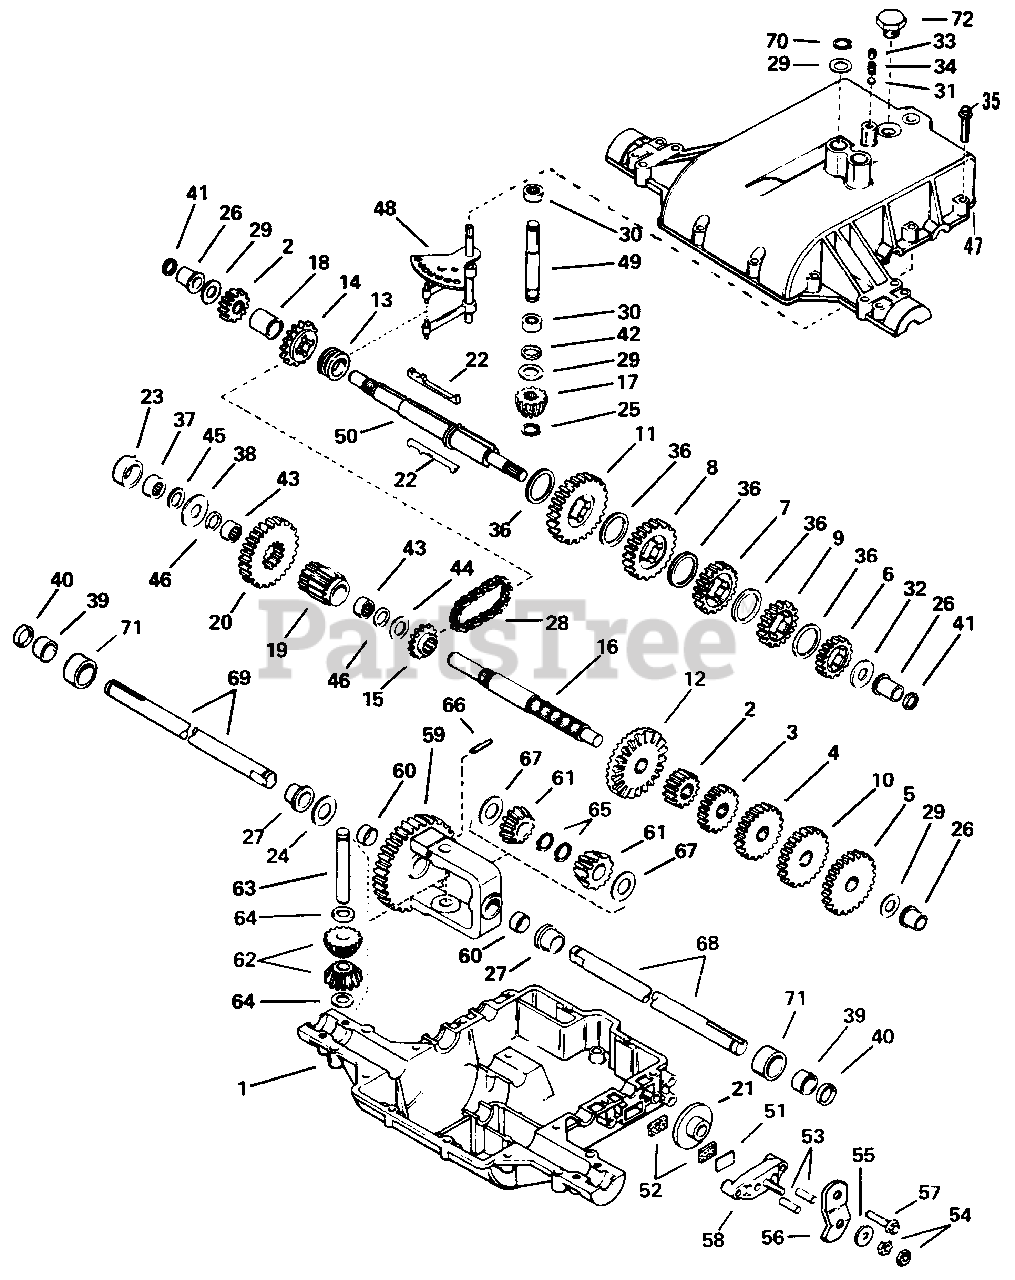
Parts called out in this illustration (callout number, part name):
1	CASE, Transaxle
2	GEAR, Spur (15 Teeth)
3	GEAR, Spur (20 Teeth)
4	GEAR, Spur (25 Teeth)
5	GEAR, Spur (30 Teeth)
6	GEAR, Spur (20 Teeth)
7	GEAR, Spur (25 Teeth)
8	GEAR, Spur (30 Teeth)
9	GEAR, Spur (22 Teeth)
10	GEAR, Spur (28 Teeth)
11	GEAR, Spur (35 Teeth)
12	GEAR, Bevel (42 Teeth)
13	COLLAR, Shift
14	SPROCKET (18 Teeth)
15	SPROCKET (19 Teeth)
16	SHAFT, Counter
17	BEVEL PINION, Input
19	PINION, Output
20	GEAR, Output
21	DISK, Brake
25	RING, Retaining
26	BUSHING, Flanged
27	BUSHING, Flanged
28	CHAIN, Roller (No. 41 chain, 24 links)
29	WASHER, Thrust
30	BEARING, Needle
31	BALL, Steel
32	WASHER, Thrust
33	SETSCREW, 3/8-16 x 3/8
35	SCREW, Hex hd., Thd. Form., 1/4-20 x 1-1/4
36	WASHER, Thrust
37	BEARING, Needle
38	WASHER, Flat
39	BEARING, Needle
40	SEAL, Oil
41	RING, Square Cut
42	RING, Square Cut
43	BEARING, Needle
44	WASHER, Flat
45	RING, Square Cut
46	RING, Square Cut
47	COVER, Transaxle
48	ROD & FORK ASSY., Shift
49	SHAFT, Input
50	SHAFT, Brake
51	PLATE, Brake Pad
52	PAD, Brake
53	PIN, Dowel
54	LOCKNUT, 5/16-24
55	WASHER, Flat
56	LEVER, Brake
57	SCREW, Hex Hd., Thd. Form., 1/4-20 x 1-1/4
58	HOLDER, Brake Pad
59	GEAR ASSY., Differential (Incl. 2 of No. 60)
61	GEAR, Bevel
62	PINION, Bevel
63	PIN, Drive
64	WASHER, Thrust
65	RING, Retaining
66	PIN, Roll
67	WASHER, Thrust
68	AXLE (15-1/8" Long)
69	AXLE (12-1/8" Long)
70	RING, Retaining
